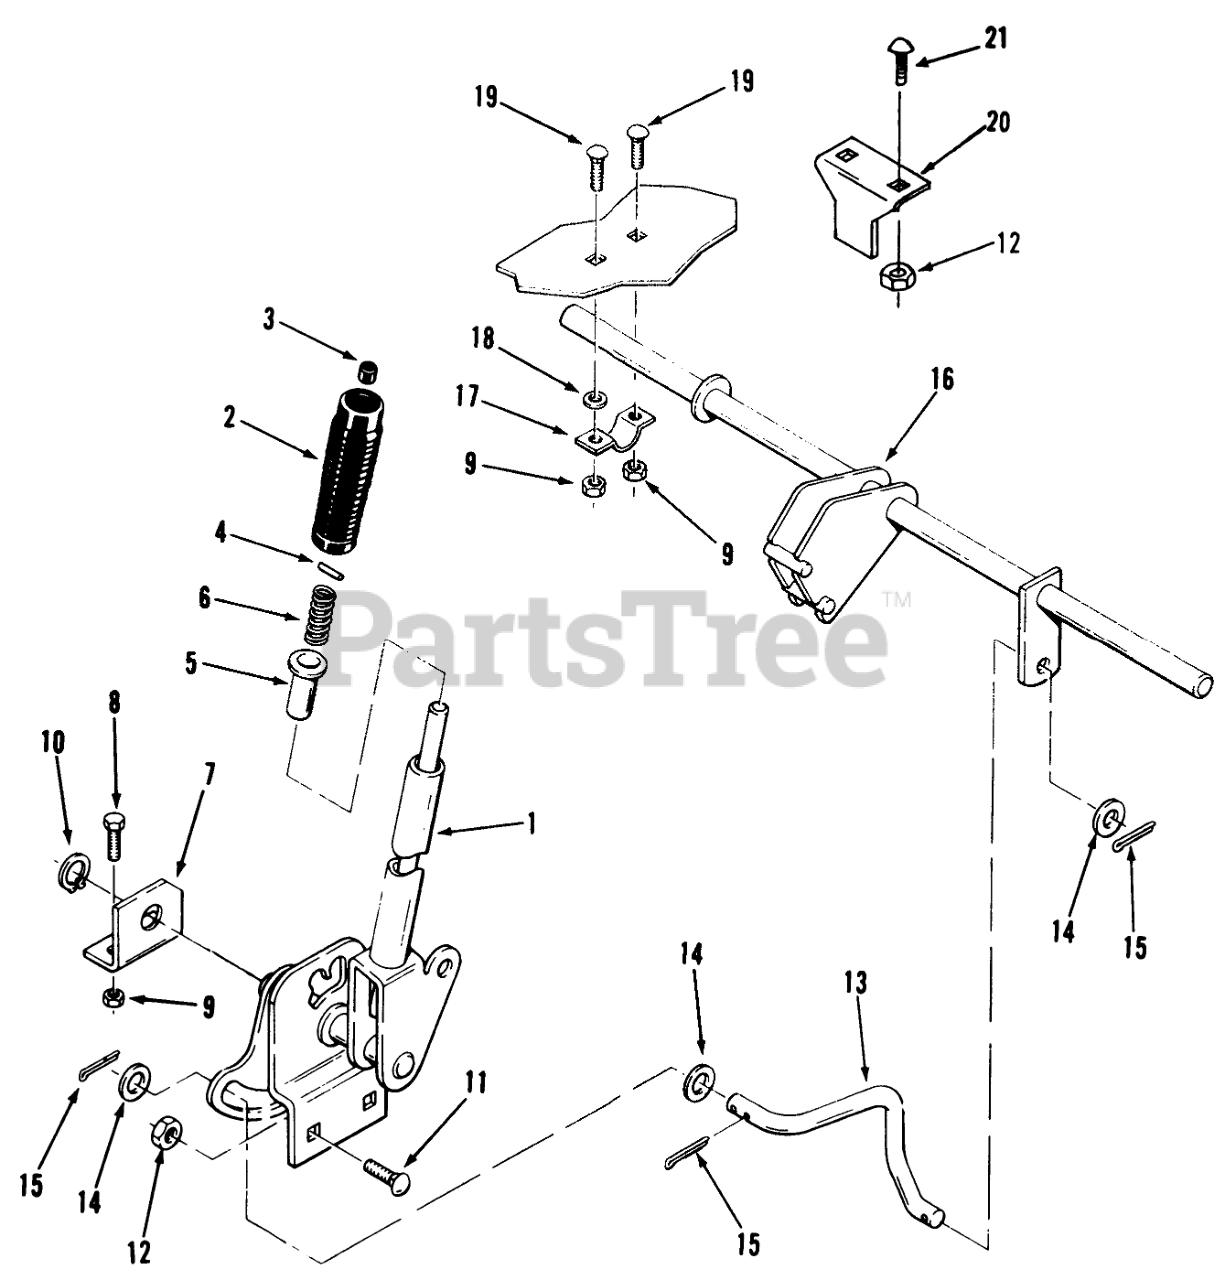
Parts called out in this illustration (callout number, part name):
1	Lift Lever
2	HANDGRIP
3	CAP-ROD, PLUNGER
4	PIN-SPIROL
5	RETAINER-SPRING
6	SPRING-COMPRESSION
7	BRACKET-INNER R
8	SCREW-HH
9	NUT-LOCK, NI
10	Retaining Ring
11	SCREW-CARR
12	NUT-LOCK, NI
13	ROD-LIFT R
14	WASHER-FLAT
15	PIN-COTTER
16	ASM-REAR LIFT R
17	CLAMP
18	WASHER-FLAT
19	Bolt
20	BRACKET STOP
21	BOLT-CARR
